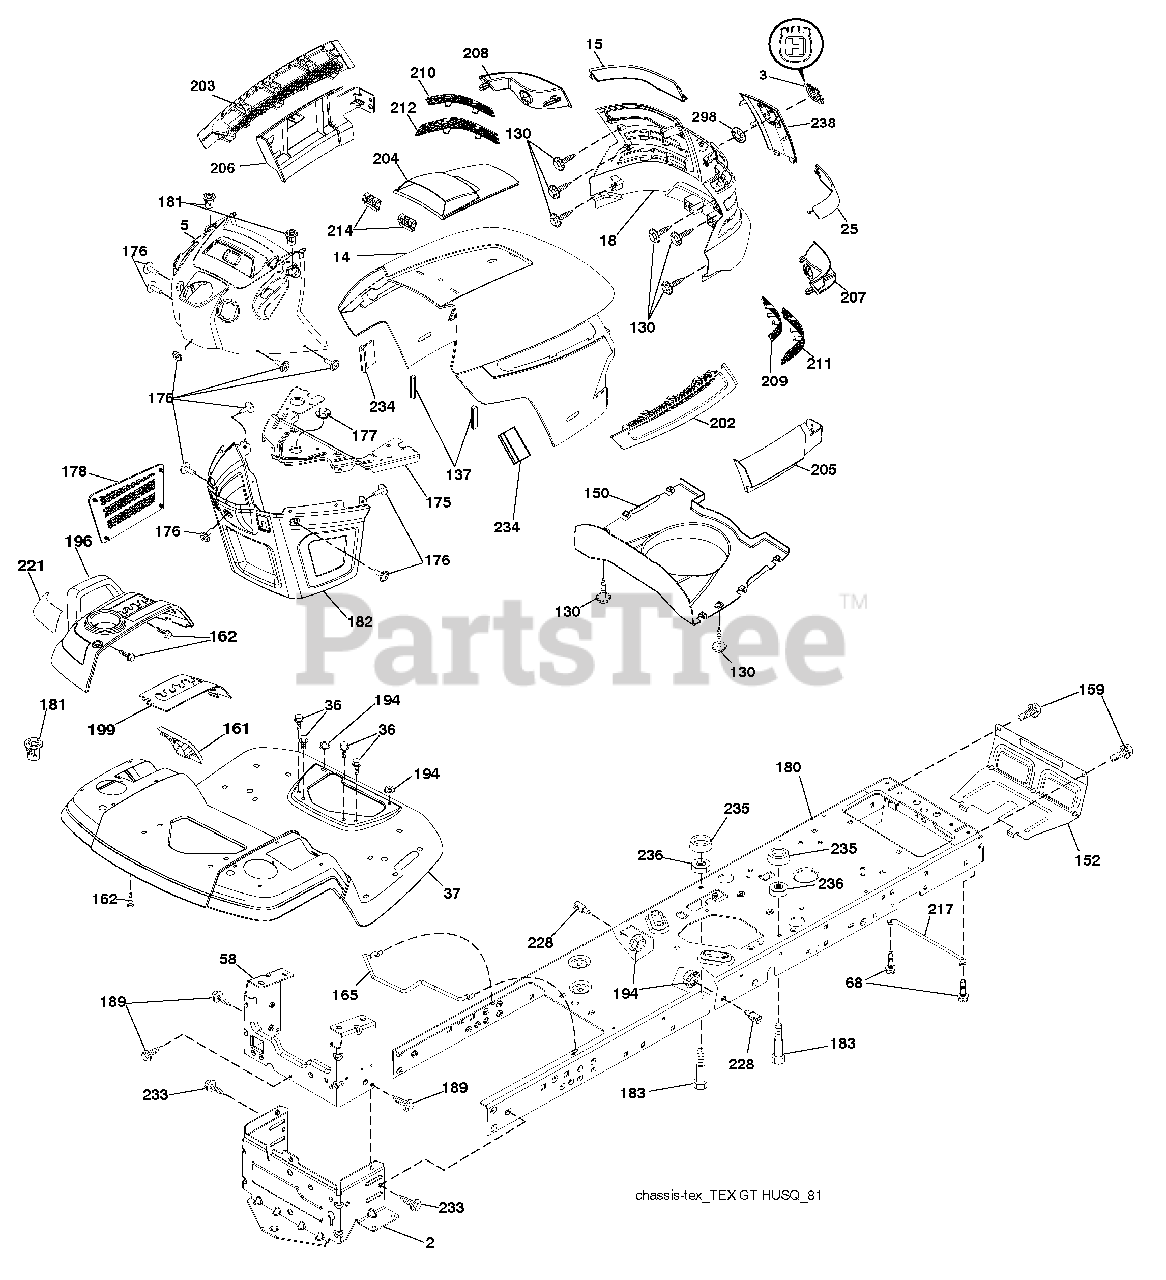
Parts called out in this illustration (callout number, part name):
2	Drawbar Lower
3	Logo
5	Dash
14	Hood
18	Grille/Lens Asm.
36	Screw 5/16-18 x 3/4
37	Fender
58	Drawbar Upper
68	Screw Thdrol 5/16-18 x 1/2
130	Screw 10 x .750 BOS Thread
137	Bumper Dash
152	Shield Browning
159	Screw 3/8-16 x 3/4
161	Window, Fuel
162	Screw Hex Wsh 1/4 x 1/2 unc
165	Support Tank Rear
175	Crossmember
176	Screw 10-24 x 5/8
177	Bushing Steering
178	Cargo Net Asm.
180	Chassis
181	Bushing Mtg. Fender Crgo
182	Dash Lower
183	Bolt 5/16-18 x1-1/4
189	Screw 5/16-18 x 3/4
194	Nut Lock Hex Flange 5/16-18
196	Console Asm Deck Lift
199	Plate Deck Lift
202	Vent Side Hood RH
203	Vent Side Hood LH
204	Vent Top Hood
205	Skirt Hood Side RH
206	Skirt Hood Side LH
209	Insert Hex Top RH
210	Insert Hex Top LH
211	Insert Hex Bottom RH
212	Insert Hex Bottom LH
214	Clip Retainer Tinner
221	Reflector LH
228	Stud Fastner
233	Bolt, Shoulder
234	Bumper Hood
235	Spacer Fender
236	Nut Lock 5/16-18 unc
238	Trim, Husq.
282	Clip Retainer Console
